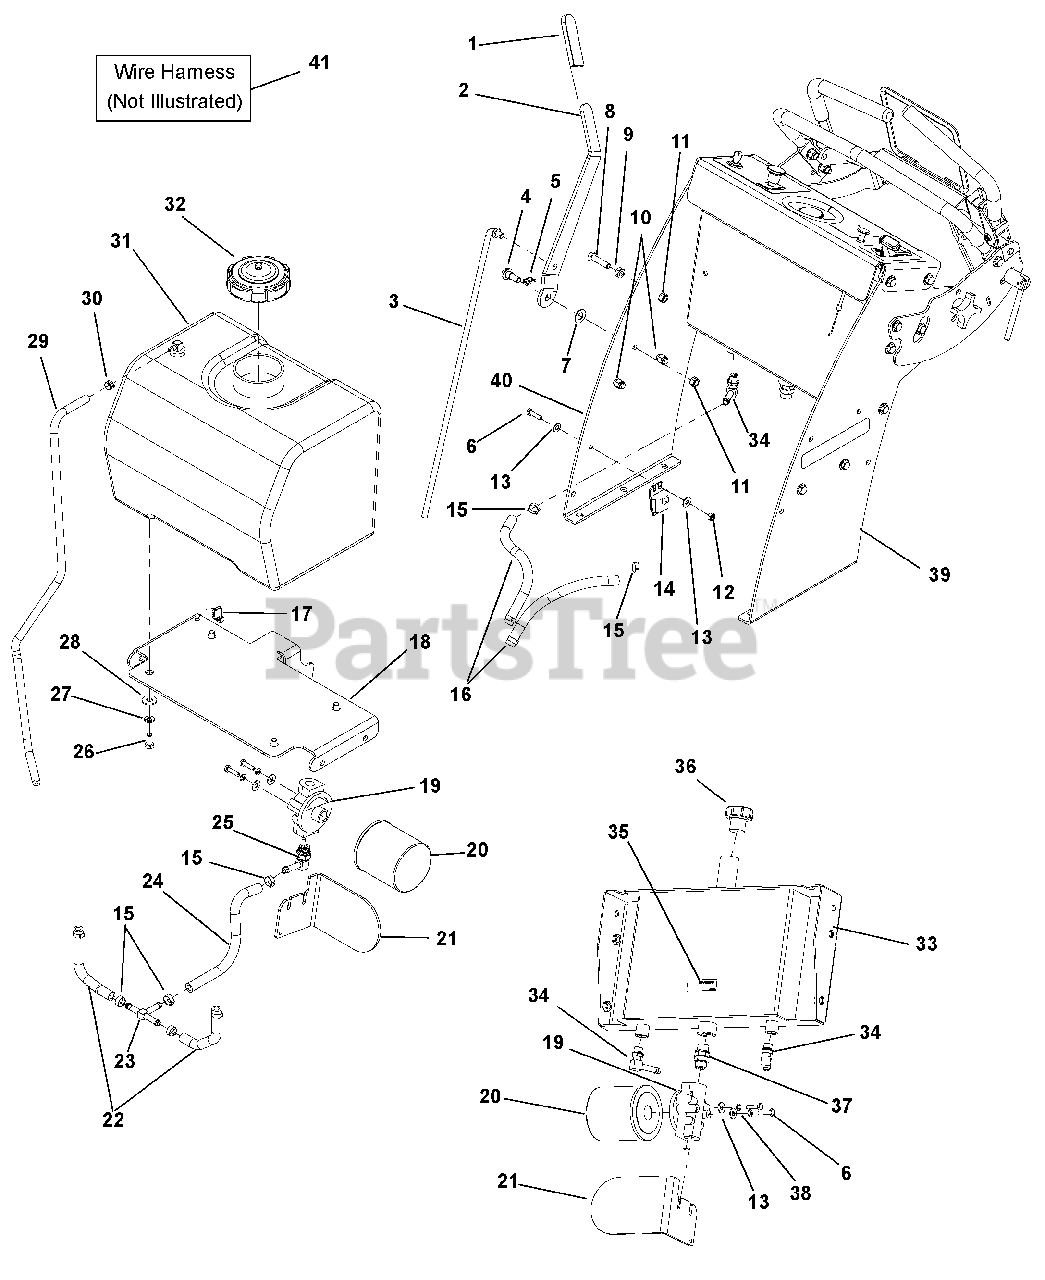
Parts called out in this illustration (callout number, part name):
1	GRIP, PVC .250 X 1.00 X 3.63
2	LEVER, HAND BRAKE FLOAT WALK
3	ROD, DRIVE CONTROL FW
4	BOLT, 1/2 X 1.06 X 3/8-16 SLD 5 Y
5	RING, RUE .375 x .054 x 1.254
6	BOLT, 1/4-20 X 1.00 HEX 5 Y
7	WASHER, .510 X 1.00 X .068 NYLON
8	BOLT, 3/8-16 X 1.50 HEX 5 Y
9	LOCKNUT, 3/8-16 WHIZ Y
10	LOCKNUT, 3/8-16 NYLOC Y
11	LOCKNUT, 3/8-16 CENTER Y
12	LOCKNUT, 1/4-20 NYLOC Y
13	WASHER, .250 REG FLAT Y
14	MODULE, ELECTRONIC
15	CLAMP, HOSE - 1/2" PINCH
16	HOSE, HYD .375 X 10
17	CABLE TIE, .15 X 8.50
18	BRACKET, FUEL TANK RMHF
19	HEAD, OIL FILTER
20	FILTER, OIL
21	GUARD, HYDRO FILTER FLWLK
22	HOSE, HYD 3/8 X 6.00
23	FTG, TUN 3/8 HOSE
24	HOSE, HYD. .375 X 9
25	FTG, 90 BRB-OR 4601-06-08
26	BOLT, 3/8-16 X .750 HEX 5 Y
27	WASHER, .375 MED SPRG LOCK Y
28	WASHER, .375 REG FLAT Y
29	HOSE, FUEL 1/4 X 30.00
30	CLAMP, HOSE - 1/2" SPRING
31	TANK, FUEL GRAVELY WALK REV G
32	CAP, FUEL
33	WLDT, TANK
34	FTG, 90 9/16 MOR X 3/8 HOSE
35	DECAL, WARNING - HOT SURFACES
36	CAP, OIL FILL BREATHER
37	STRAIGHT UNION SAE 8
38	WASHER, .250 MED SPRG LOCK Y
39	WLDT, LH UPRIGHT FLOAT WALK
40	WLDT, RH UPRIGHT FLOAT WALK
41	HARNESS, WIRE NON ELEC ST WALK
